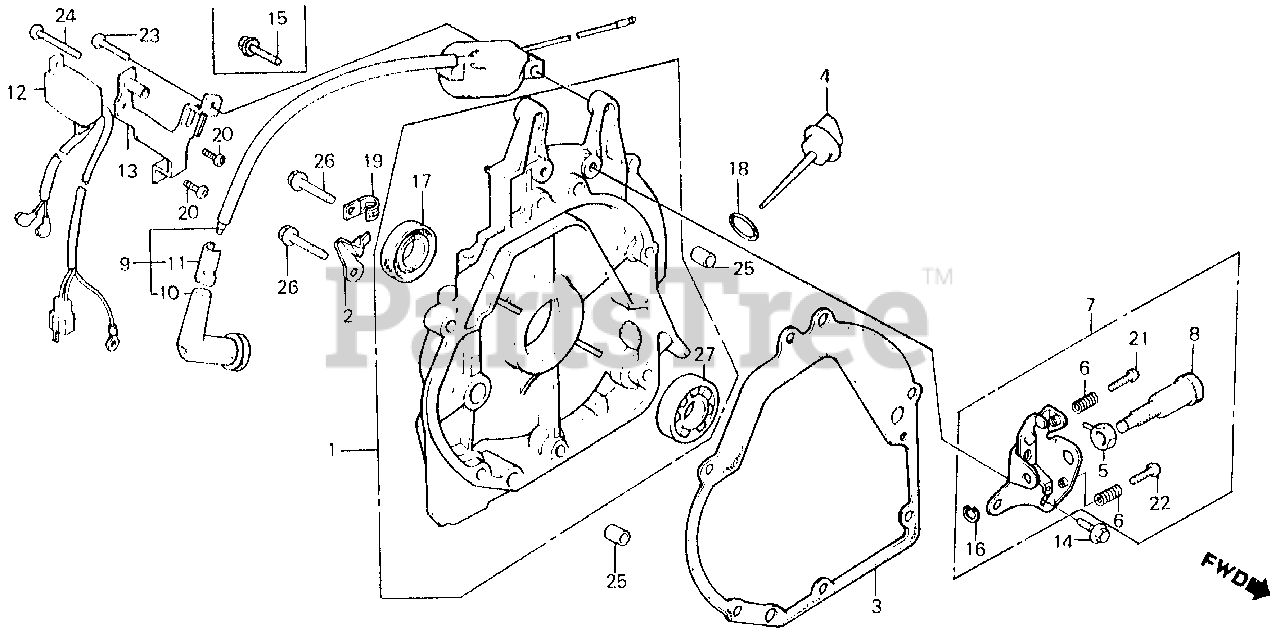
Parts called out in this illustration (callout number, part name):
1	COVER ASSY., CRANKCASE (NOT AVAILABLE)
2	SUPPORT, FUEL TUBE
3	GASKET, CASE COVER (NOT AVAILABLE)
4	CAP, OIL FILLER (NOT AVAILABLE)
5	NUT, CONTROL ADJUSTING
6	SPRING, CONTROL ADJUSTING
7	CONTROL ASSY. (NOT AVAILABLE)
8	SHAFT, CONTROL (NOT AVAILABLE)
9	COIL ASSY., IGNITION (NOT AVAILABLE)
10	CAP, IGNITION (TOYO)
11	TERMINAL, PLUG
14	BOLT, FLANGE (5X10)
15	BOLT, FLANGE (5X18)
16	CIRCLIP (5MM)
17	OIL SEAL (15X24X5)
18	O-RING (16MM)
19	CLIP A, WIRE
21	SCREW, PAN (4X26)
22	SCREW, PAN (4X20)
25	PIN A, DOWEL (8X14)
26	BOLT, FLANGE (6X25)
27	BEARING, RADIAL BALL (6202)
